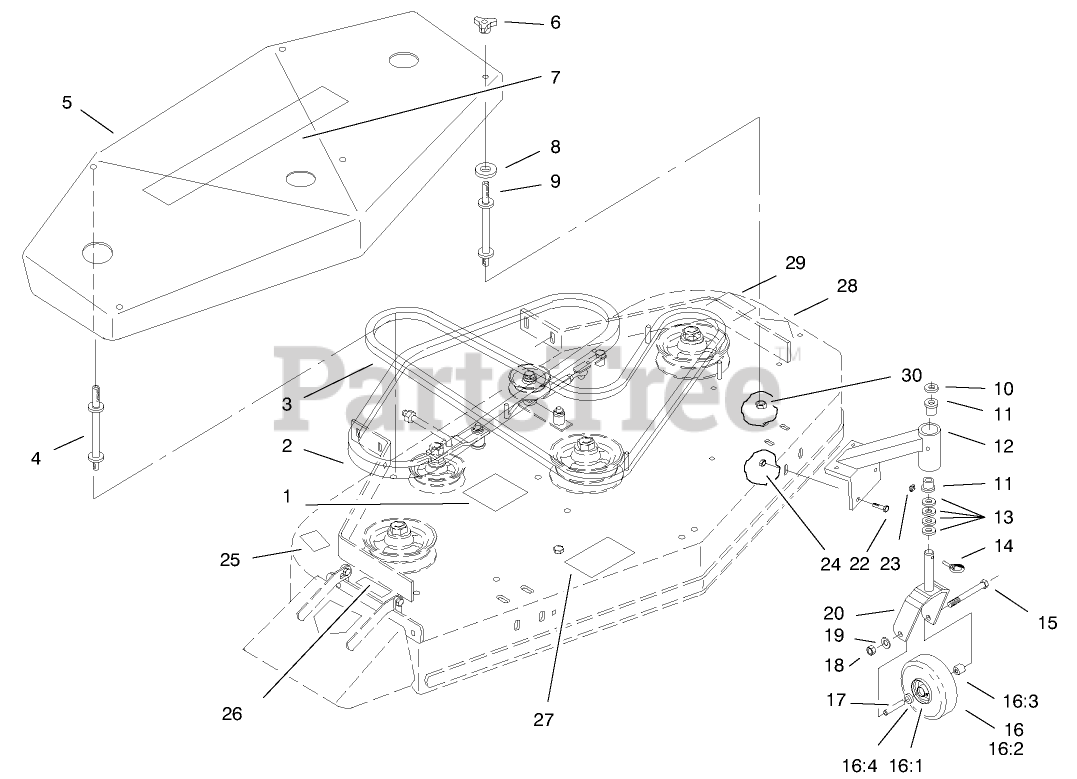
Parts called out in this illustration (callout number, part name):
1	Decal-Belt Routing
2	Belt-Blade Drive
3	Belt-Blade Drive
4	Stud-Belt Shield(Long)
5	Cover-Belt
6	Knob
7	Decal
8	Washer
9	Stud-Belt Shield(Short)
10	Washer
11	Bearing-Flanged
12	Support-Caster
13	Spacer
14	Pin
15	SCREW-HH
16	Tire and Wheel ASM
16:1	Wheel Hub ASM
16:2	Tire
16:3	Bearing
16:4	Bushing
17	Spacer
18	NUT-HH
19	WASHER-LOCK
20	Fork
22	SCREW-HH
23	Zerk
24	NUT-FLANGE
25	DECAL
26	DECAL-DANGER
27	DECAL-DANGER, THROWN OBJECT
28	DECAL-DANGER
29	Decal-Torque
30	NUT-HF
